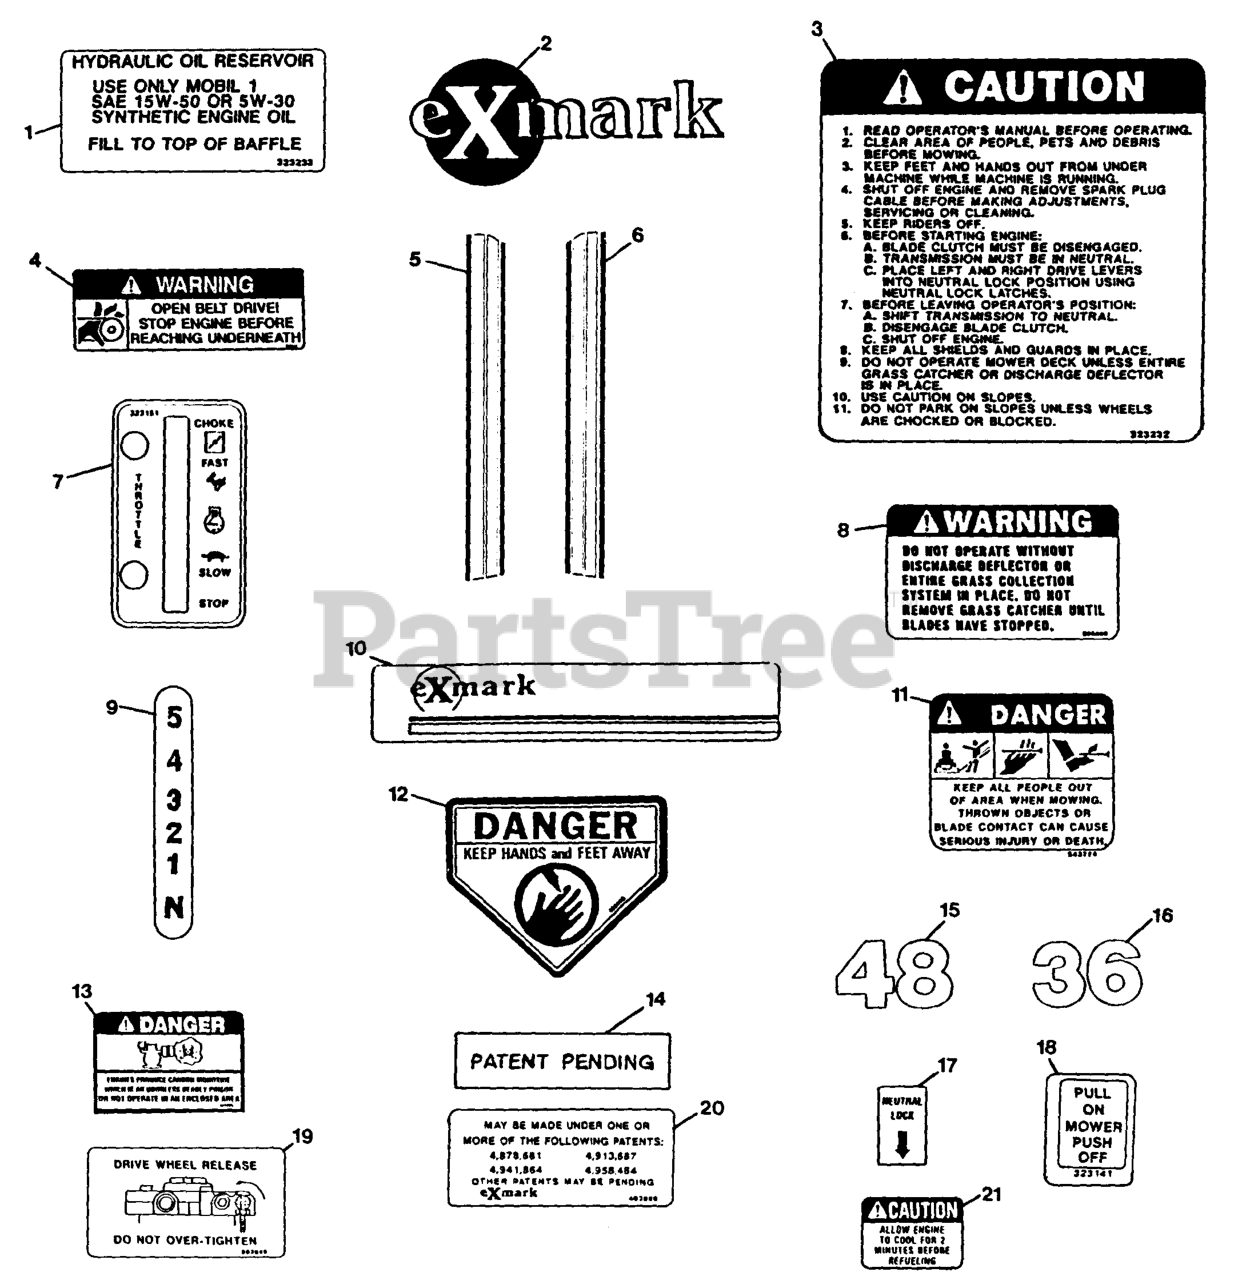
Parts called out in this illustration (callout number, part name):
3	DECAL,INSTRUCTIONAL
4	DECAL,BELT DRIVE
8	DECAL-WARNING, DISCHARGE
9	DECAL - SHIFTER
11	DECAL-DANGER
12	DECAL-DANGER
14	Decal - Patent Pending
17	DECAL,NEUTRAL LOCK
19	DECAL,DRIVE RELEASE
